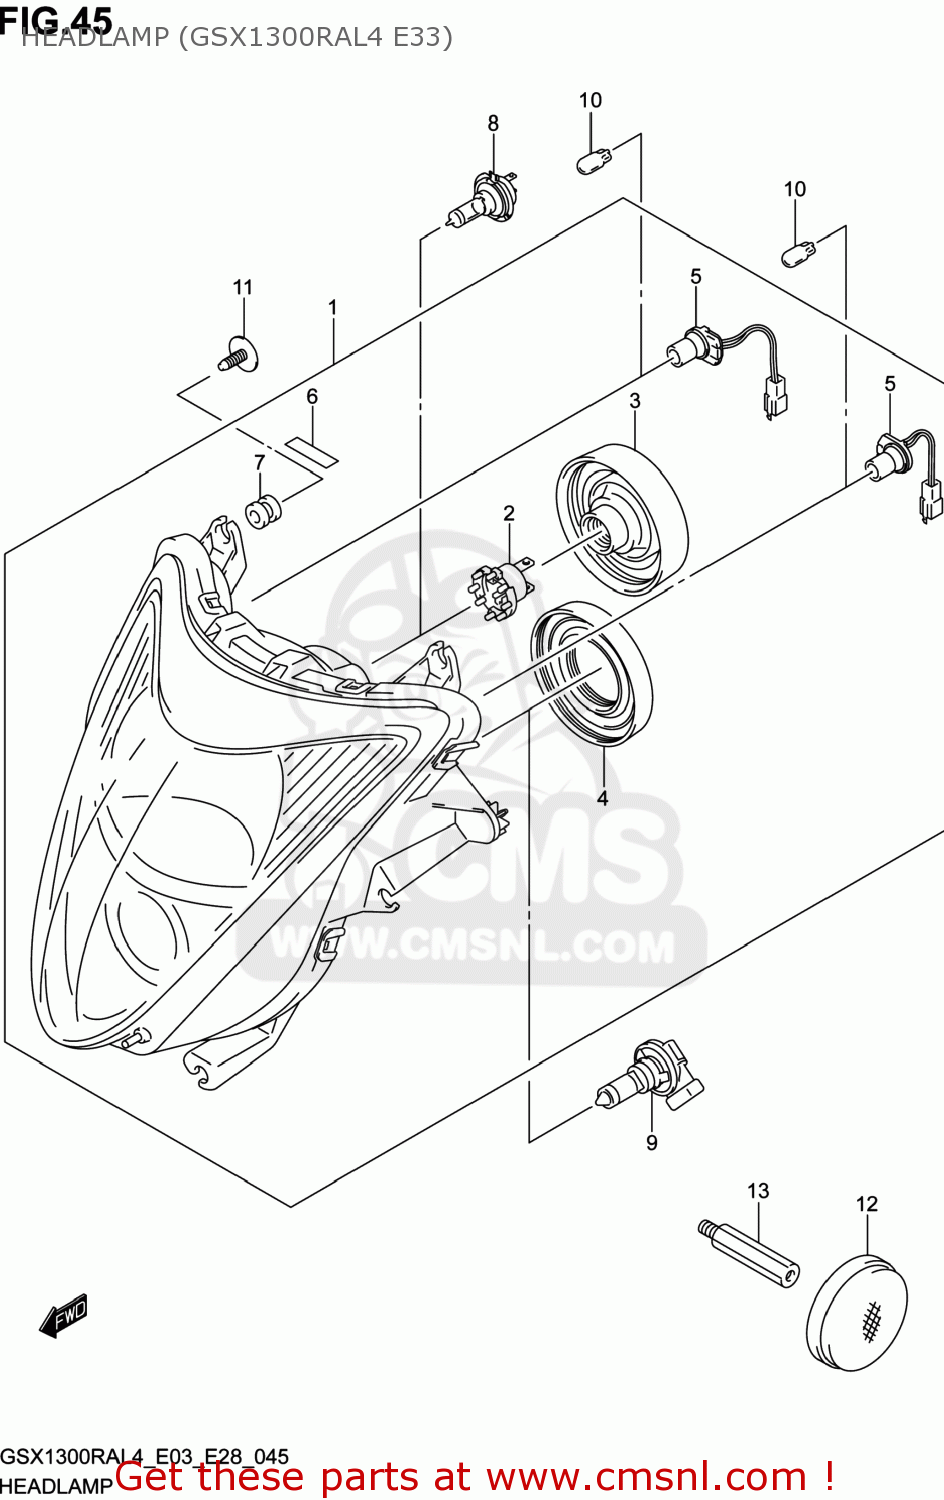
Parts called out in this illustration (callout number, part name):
1	HEADLAMP ASSY
2	ADAPTER ASSY
3	COVER
4	COVER
5	CORD ASSY
6	TAPE,FR TURNSIGNAL
7	CUSHION
8	BULB(12V55W/H7/PX26D/PHILIPS)
9	BULB(12V65W,H9)
10	BULB(12V5W)
11	SCREW(5X15)
12	REFLEX REFLECTOR ASSY,FR SIDE
13	BOLT
